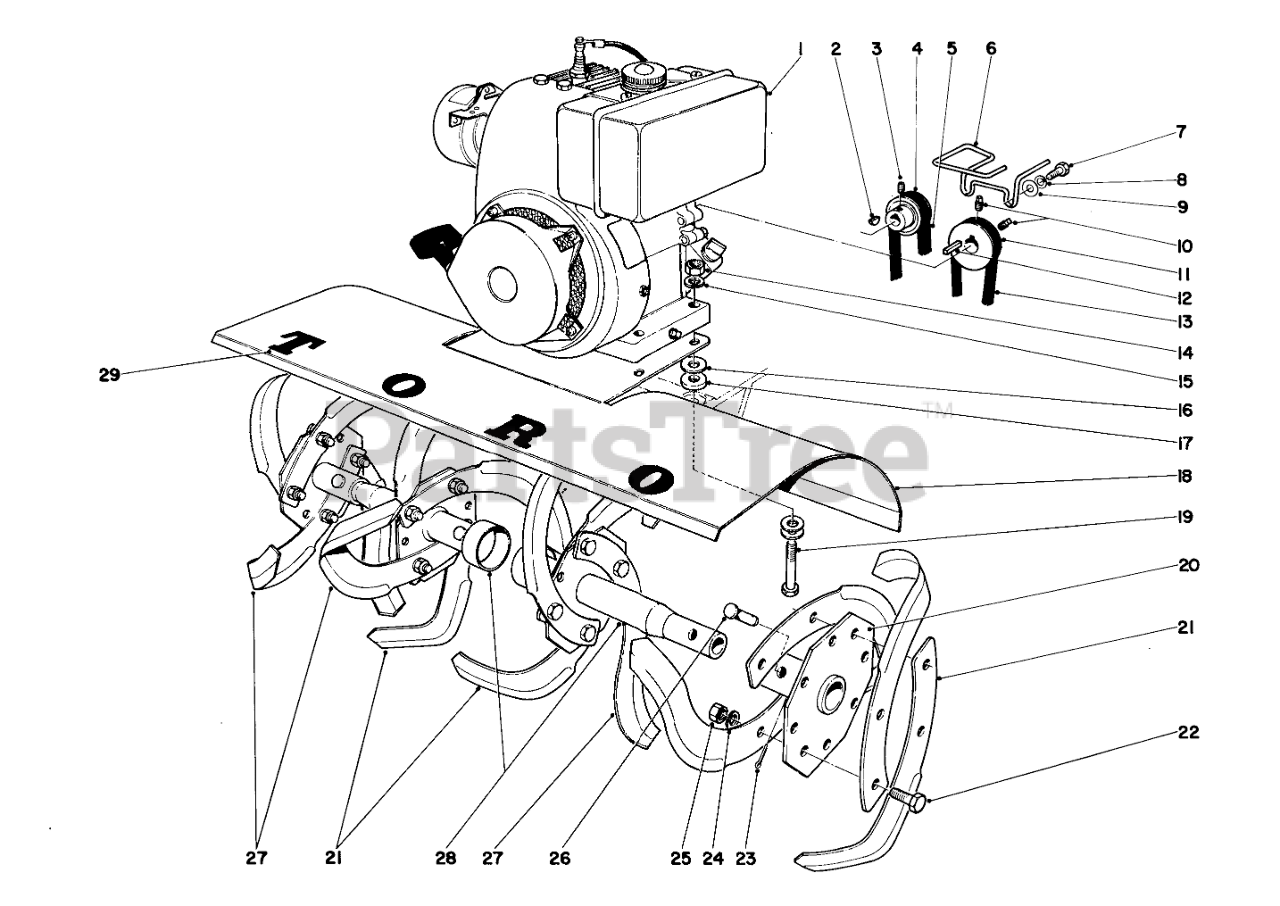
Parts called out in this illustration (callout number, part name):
1	Engine
2	KEY-WOODRUFF
3	SCREW-SET
4	Pulley
5	V-BELT
6	Belt Guide
7	SCREW-HH
8	WASHER-LOCK
9	WASHER-FLAT
10	SCREW-SET, HSH
11	Engine Pulley
12	KEY-SQUARE
14	NUT-HEX
15	WASHER-LOCK
16	WASHER-FLAT
17	WASHER-FLAT
18	Shield
19	SCREW-HH
20	Axle Hub
21	RH TINE
22	SCREW-HH
23	PIN-COTTER
24	WASHER-LOCK
25	NUT-HEX
26	TINE PIN
27	LH TINE
28	Axle Hub
29	Decal
